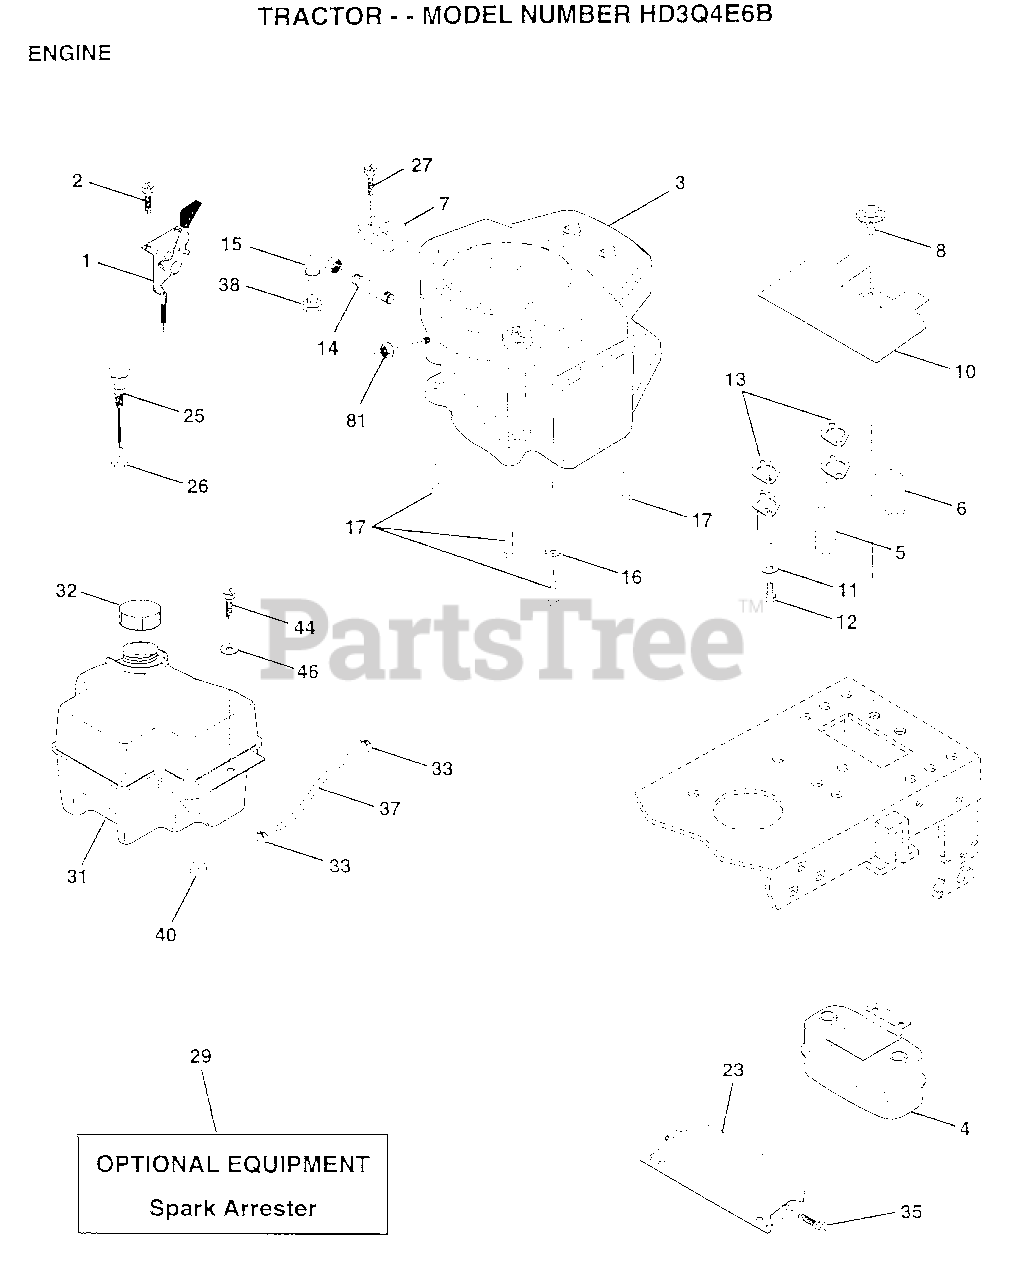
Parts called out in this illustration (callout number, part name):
1	CONTROL THRT 35.5
2	SCREW LT
4	MUFFLER.TW.LOTONE
5	EXHAUST.B&S.18.LH
6	EXHAUST.B&S.18.RH
7	CLAMP.TUBE.DBL.EN
8	BOLT.5/16-18.UNC
10	SHIELD.HEAT.
13	GASKET MUFFLER
14	PIPE NIPPLE LT
15	ELBOW
16	LOCKWASHER
17	SCREW LT
25	CONTROL.CHOKE.37
26	"NUT,KEPS 3/8-24IM"
27	"SCREW-TT,10-32 FL"
32	CAP ASM FUEL
33	HOSE CLAMP
35	SCREW
37	LINE FUEL
44	SCREW HEX CRT
46	WASHER
81	NUT
